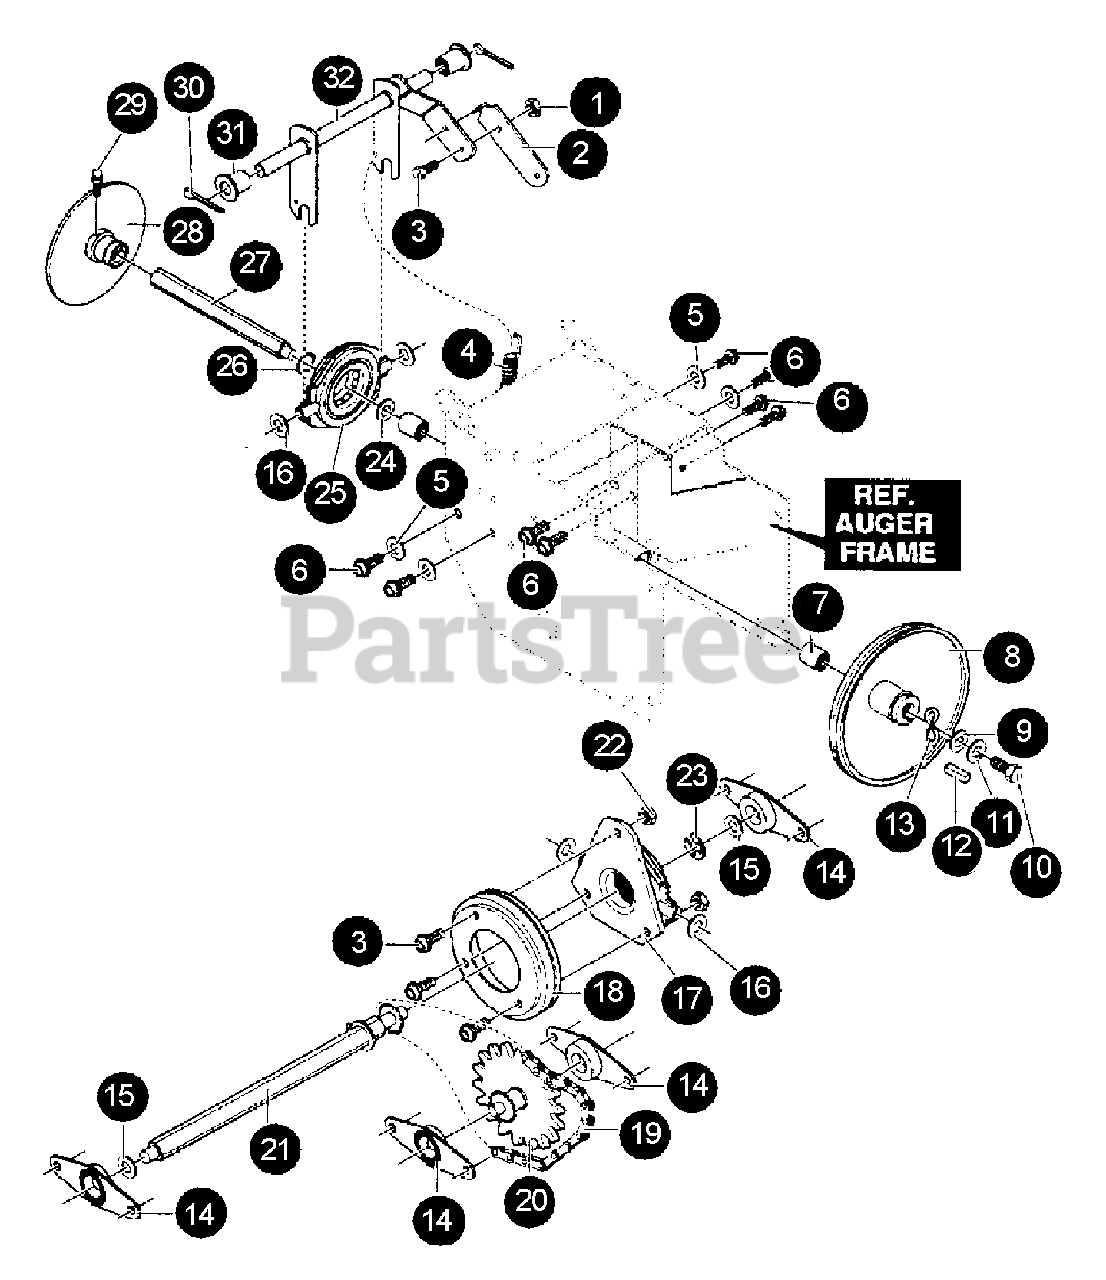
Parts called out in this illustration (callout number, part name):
1	NUT - 1/4-20
2	LEVER, SPRING TRAC CL
3	SCREW - 1/4-20 X 5/8"
4	SPRING, RETURN
5	LOCKWASHER
6	SCREW - 5/16-18 X 1/2"
7	BEARING, BALL - 6203
8	PULLEY, V3L6.50X.56
9	WASHER, FLAT .281X1.00X.063
10	SCREW - 1/4-20
11	LOCKWASHER
12	KEY, SQUARE .18SQX.63LG
13	WASHER - SPRING
14	BEARING KIT
15	WASHER, SP .502X.75X.0605
16	WASHER - .53X1.00X.063
17	BEARING, TRUNION CLUTCH
18	FRICTION DISC WHEEL ASSY
19	CHAIN, ROLLER #42X40P
20	JACK ASSY #41-36T & 7T
21	HEX ASSY #40-8TW/PBRG
22	NUT - 1/4-20 -- KEPS
23	RING, RETEX
24	WASHER, FLAT .680X1.12X.060Z
25	BEARING, TRUNION 1.25 ID
26	RING, RETEX
27	SHAFT, HEX TRACTION
28	FRICTION WHEEL DISC ASSY
29	FITTING, GREASE -.25-28X1.12LG
30	PIN, SPLIT - 1-1/4 X 1"
31	BEARING, FLANGE
32	TRACTION CLUTCH LEVER ASSY
